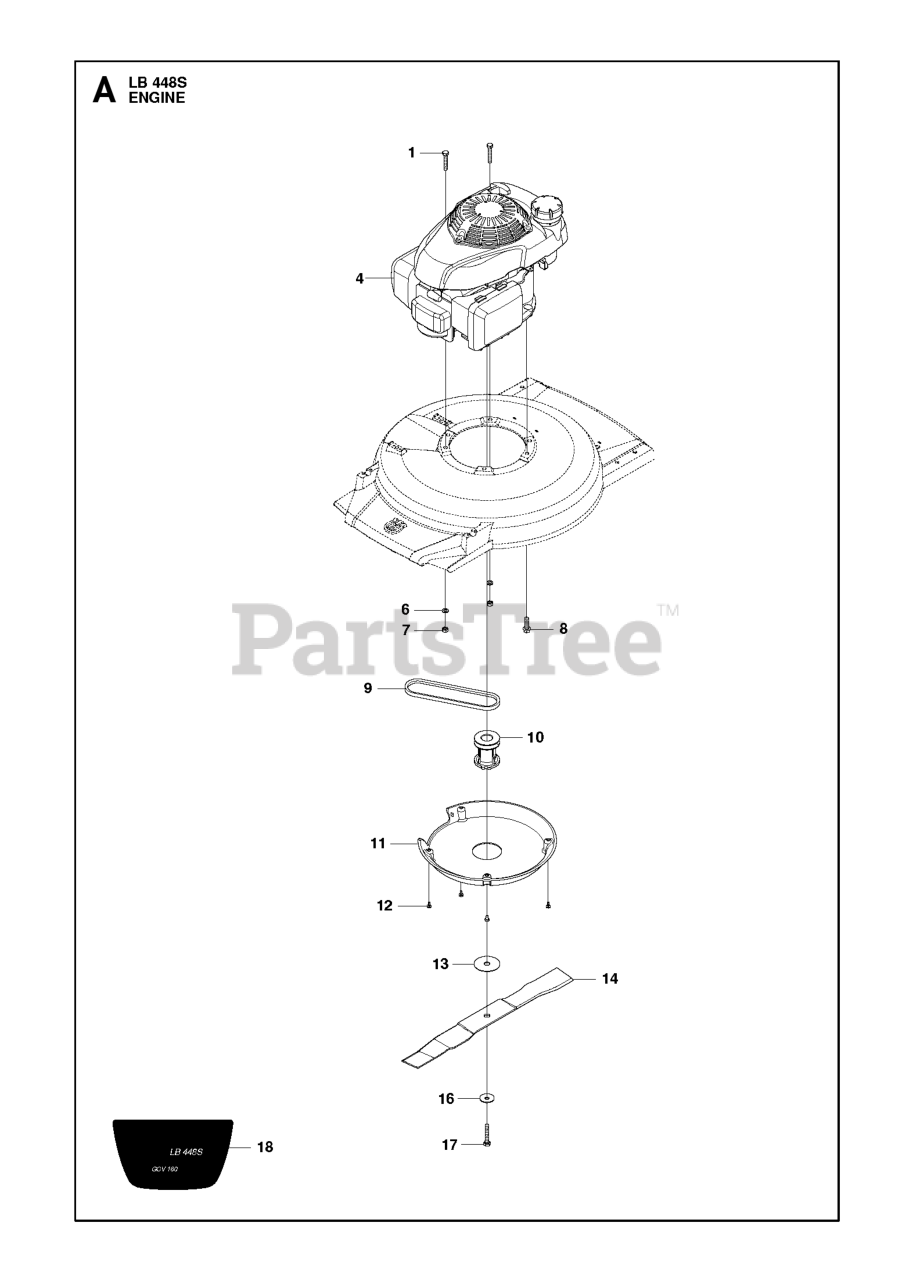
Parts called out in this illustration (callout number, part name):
6	WASHER BRB 8.4X17
7	LOCKNUT M8
12	SCREW ITXPANTT M5X10 ZPB (A00
